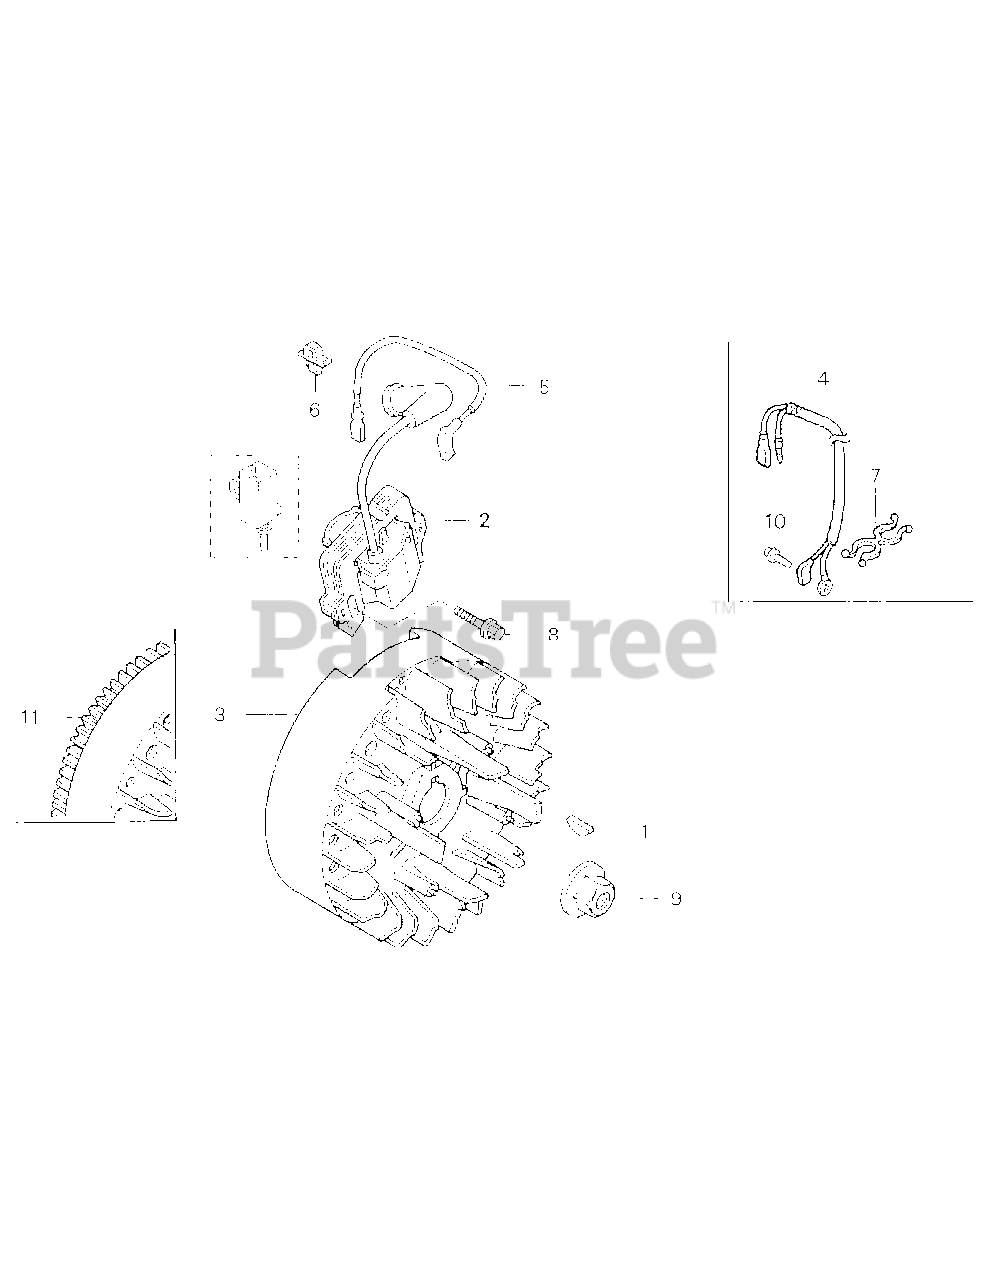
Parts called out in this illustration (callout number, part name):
1	Key, Special Woodruff, 25X18
2	Coil Assy., Ignition (Phelon)
3	Flywheel Comp. (Phelon)
5	Cord, Stop Switch
6	Holder, Stop Switch Cord
6	Holder, Wire (Fastex)
8	Bolt, Flange, 6X20 (Ct200)
9	Nut, Flange, 14Mm
